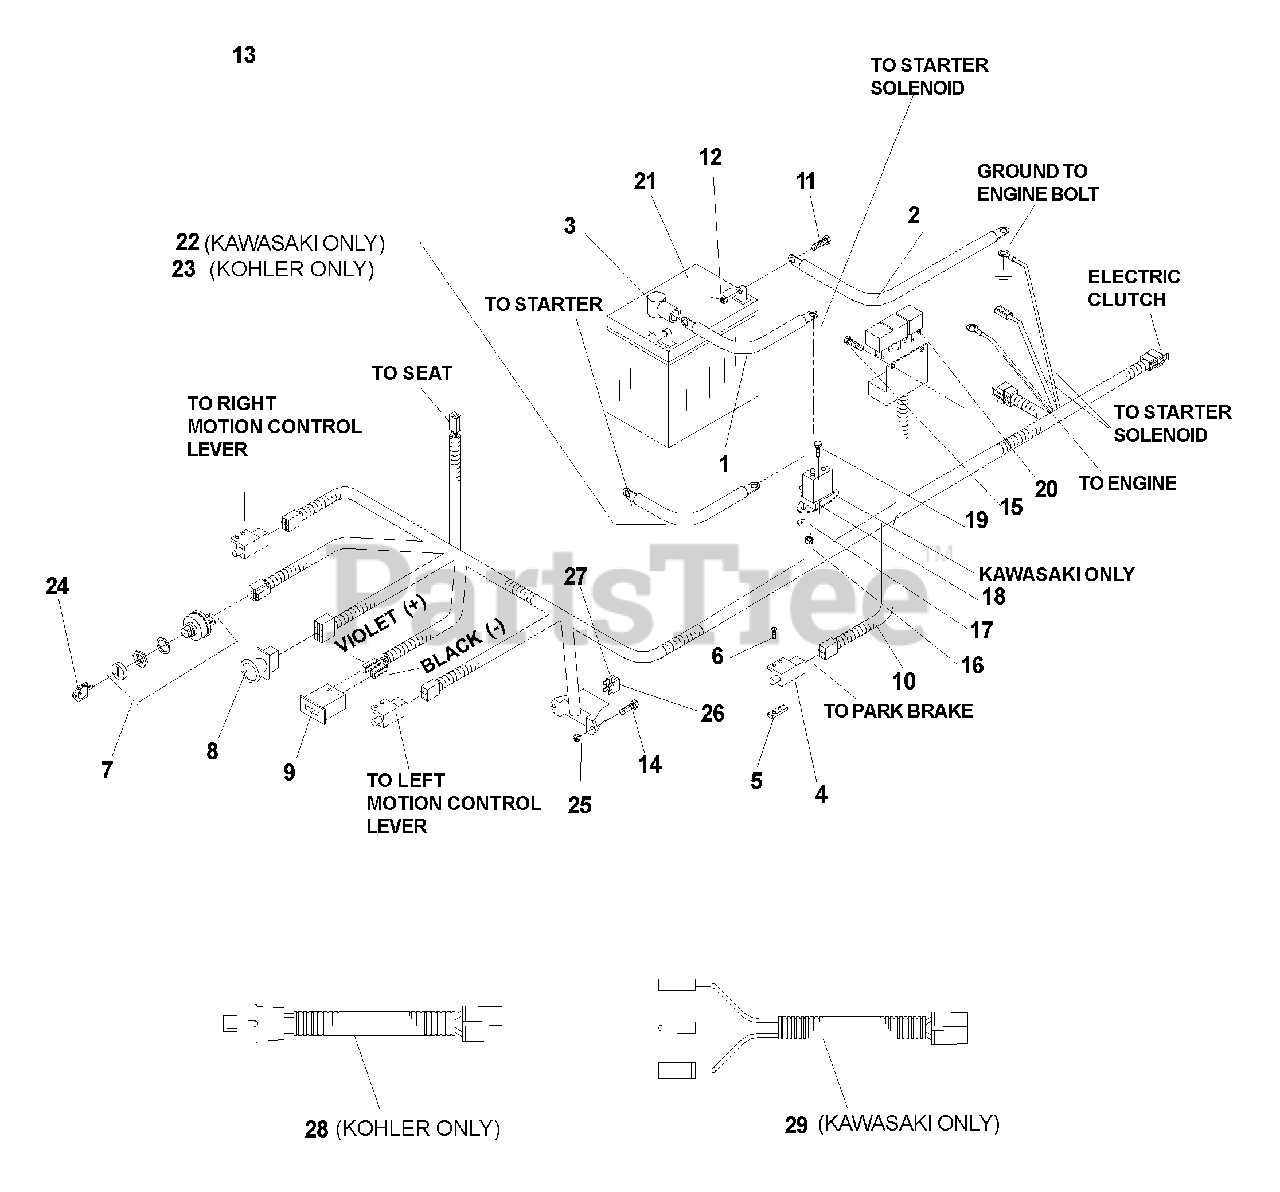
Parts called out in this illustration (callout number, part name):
1	POSITIVE CABLE
2	NEGATIVE CABLE
4	INTERLOCK SWITCH
5	TAPPED PLATE
6	SCREW, #10-24 X 5/8
7	IGNITION SWITCH
8	BLADE SWITCH
9	HOUR METER
10	FRAME HARNESS
11	HCS, 5/16C X 3/4
12	NUT, 5/16C, NYLOC
13	NUT, #10-24, NYLOC
14	SCREW, #10-24 X 7/8
15	SCREW, #10-24 X 5/8, WASH HD
16	NUT, , 1/4C, CENTERLOCK
17	LOCKWASHER, 1/4, INTERNAL TOOTH
18	SOLENOID
19	HCS, 1/4C X 5/8
21	BATTERY, DRY
22	CABLE POSITIVE
23	CABLE POSITIVE
24	KEY, PADDED
25	NUT, #10-24, NYLOC
26	FUSE, 7.5 AMP, 32 VOLT, ATO
27	FUSE, 20 AMP, 32 VOLT, ATO
28	PIGTAIL
29	PIGTAIL
